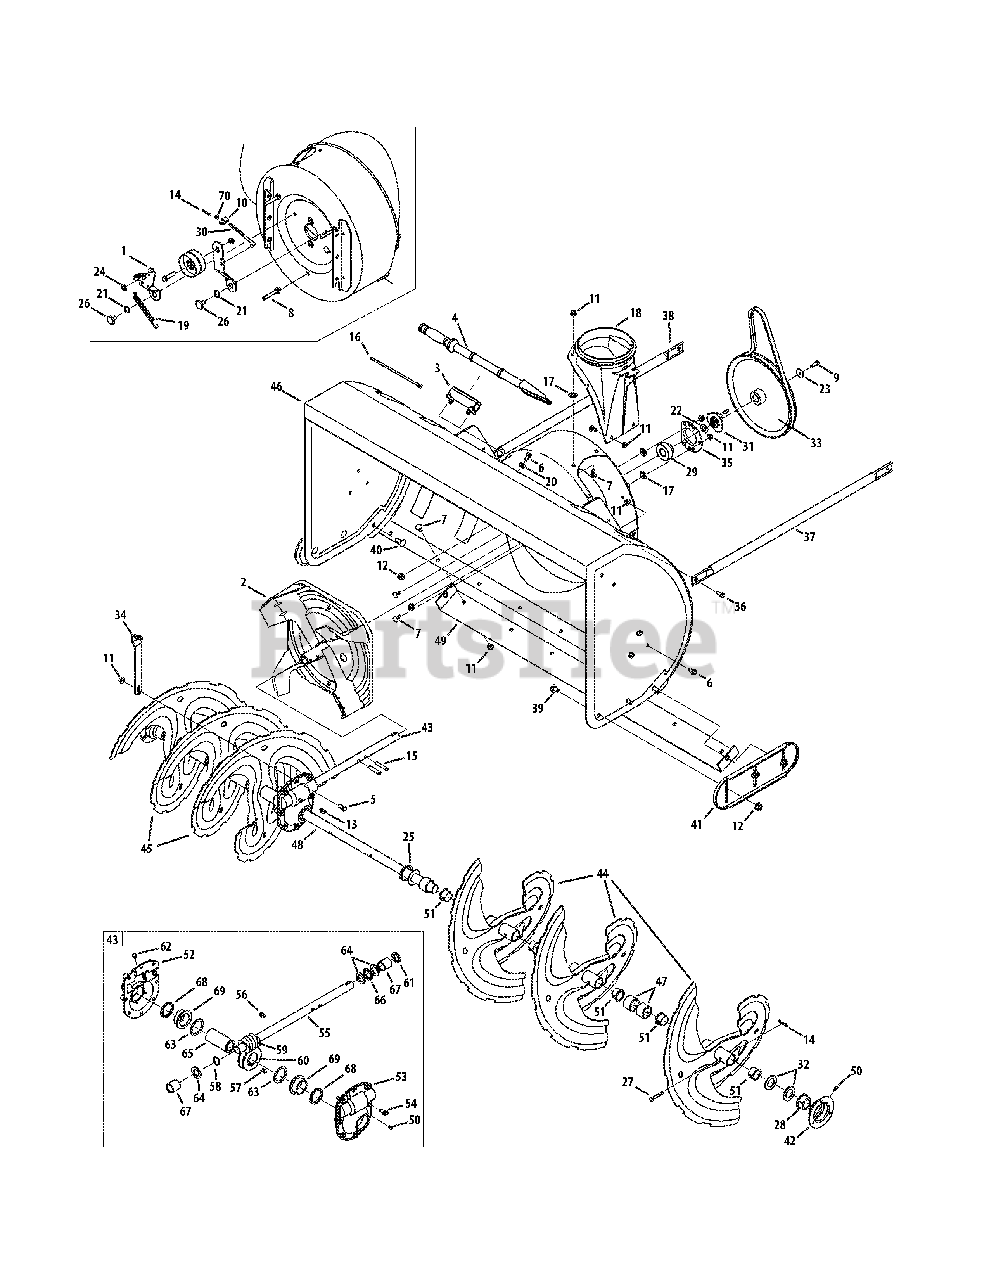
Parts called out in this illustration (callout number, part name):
1	Bracket Assembly, Auger Brake
2	Impeller, 16"
3	Clip, Mounting
4	Tool, Clean-out
5	Screw, Hex Cap, 5/16-18 x 1.0 Gr5
6	Screw, 5/16-18 x .750
7	Screw, Carriage, 5/16-18 x .75
8	Screw w/Stud, 5/16-18 x .4300
9	Screw, Hex Cap Lock, 5/16-24, 875
11	Nut, Hex Flange Lock, 5/16-18
12	Nut, Hex Flange Lock, 3/8-16
13	Key, Woodruff, 1/4 x 3/4
14	Pin, Bow-tie Cotter
15	Pin, Spiral, 5/16 x 1.75
16	Cable Tie
17	Nut, Push
18	Adapter, Chute, 6"
19	Spring, Extension
20	Washer, Flat, .349 x .879 .063
21	Washer, Wave, .625 x .885 x .015
22	Washer, Bell., .78 x 1.49 x .06
23	Washer, Flat, .34 x 1.5 x .15 Ht.
24	Washer, .344 x .75 x .12
25	Washer, 1.01 x 1.86 x .06
26	Screw, Shoulder, .625 x .17
27	Pin, Shear, .25 x 1.75
28	Bearing, Flange w/Flats
29	Bearing, Self Aligning
30	Rod, Auger Idler
31	Adapter, Pulley w/Pins
32	Spacer, 1.004 x 1.375 x .25
33	Pulley, Auger Drive, 10.0
34	Bracket, Gear Box Support
35	Housing, Bearing
36	Screw, 5/16-18 x .75 GR5
37	Tube, Support , LH
38	Tube, Support, RH
39	Screw, Carriage, 3/8-16 x .75
40	Screw, Carriage, 3/8-16 x 1.00
42	Housing, Bearing
43	Gear Box Assembly
44	Spiral Assembly, LH
45	Spiral Assembly, RH
46	Housing, Auger - 45"
47	Spacer, 1.50 x 1.00 x 1.00
48	Axle, Spiral
49	Shave Plate, 45"
50	Grease Fitting, 3/16
51	Flange Bushing
52	Housing Assembly, Auger, RH
53	Housing Assembly, Auger, LH
54	Screw, LD, 5/16-18 x .750
55	Auger Drive Shaft
56	Key, Hi Pro, 3/16 x 3/4
57	Key, 1/4 x 3/4 Dia.
58	External Retainer Ring
59	Gear, Worm
60	Gear, Worm, LH
61	Seal, Oil
63	Wash, Flat, 1.52ID x 2.0 OD
64	Wash, Flat, .88 ID x .38 OD
65	Worm Gear Shaft
66	Bearing, Thrust
69	Flange Bearing
70	Jam Nut, 5/16-18
